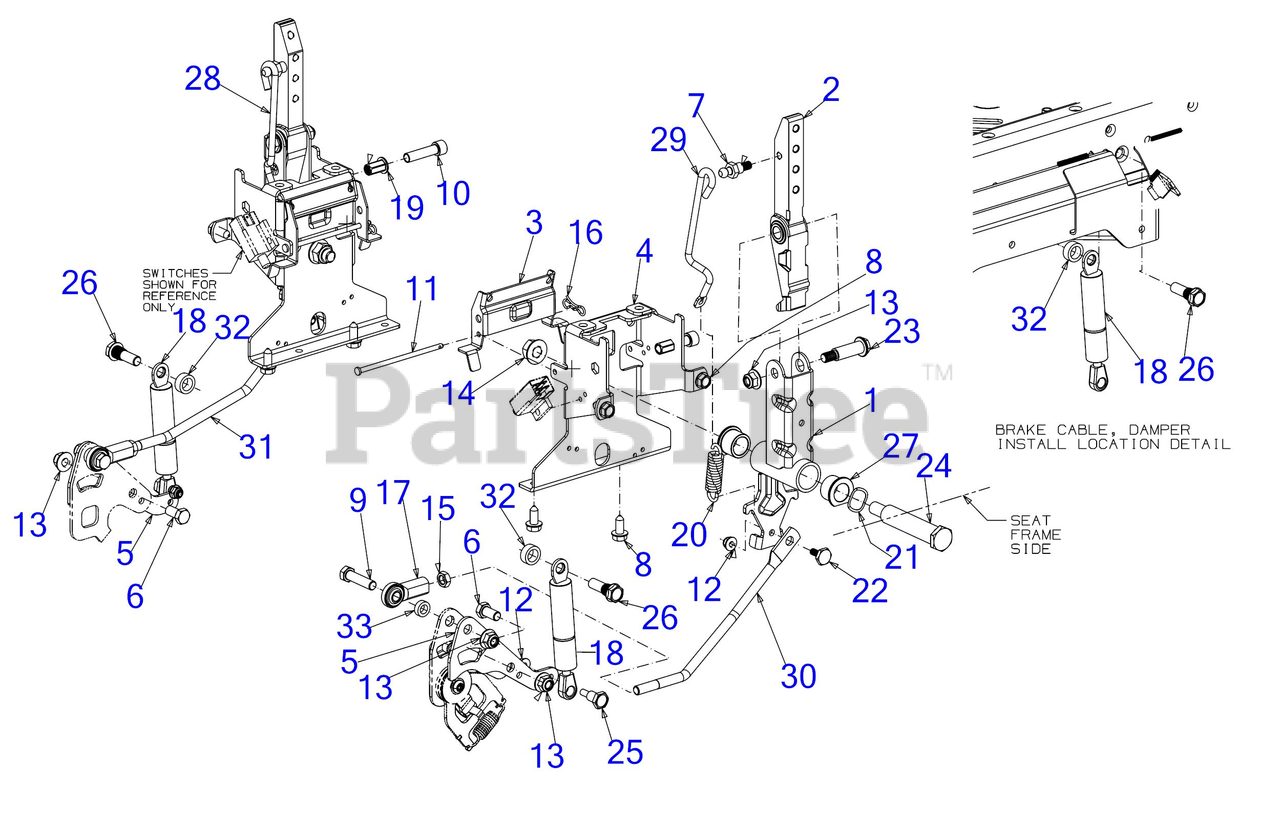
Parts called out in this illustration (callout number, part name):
2	LOWER LAP BAR ARM ASSEMBLY
6	HEX SCREW 3/8-16 x .75
7	SCREW 5/16-18 x .48
8	SCREW 5/16-18 x .750
9	SCREW 3/8-16 x 1.50
10	SCREW 3/8-16 x 1.50
11	PIN .188 x 4.1
12	FLANGE LOCK NUT
15	HEX JAM NUT 3/8X24
16	BOW TIE COTTER PIN 1/4-5/16
17	BALL JOINT
18	HYD DAMPER CYLINDER
19	NUT RIVET
20	EXTENSION SPRING
21	WAVE WASHER .785X1.00X.012
22	SHOULDER SCREW
23	SHOULDER BOLT .498 DIA x 1.296 LG
24	SHOULDER BOLT .750 DIA x 3.25 LG
25	SHOULDER BOLT .395 DIA x .56 LG
26	SHOULDER BOLT .395 DIA X.83 LG DOG
27	FLANGE BEARING
28	LAPBAR DETENT ROD (LH)
29	LAPBAR DETENT ROD (RH)
30	HYDRO CONTROL ROD (RH)
31	HYDRO CONTROL ROD (LH)
33	SPACER-.380 ID X.625 OD x .227
